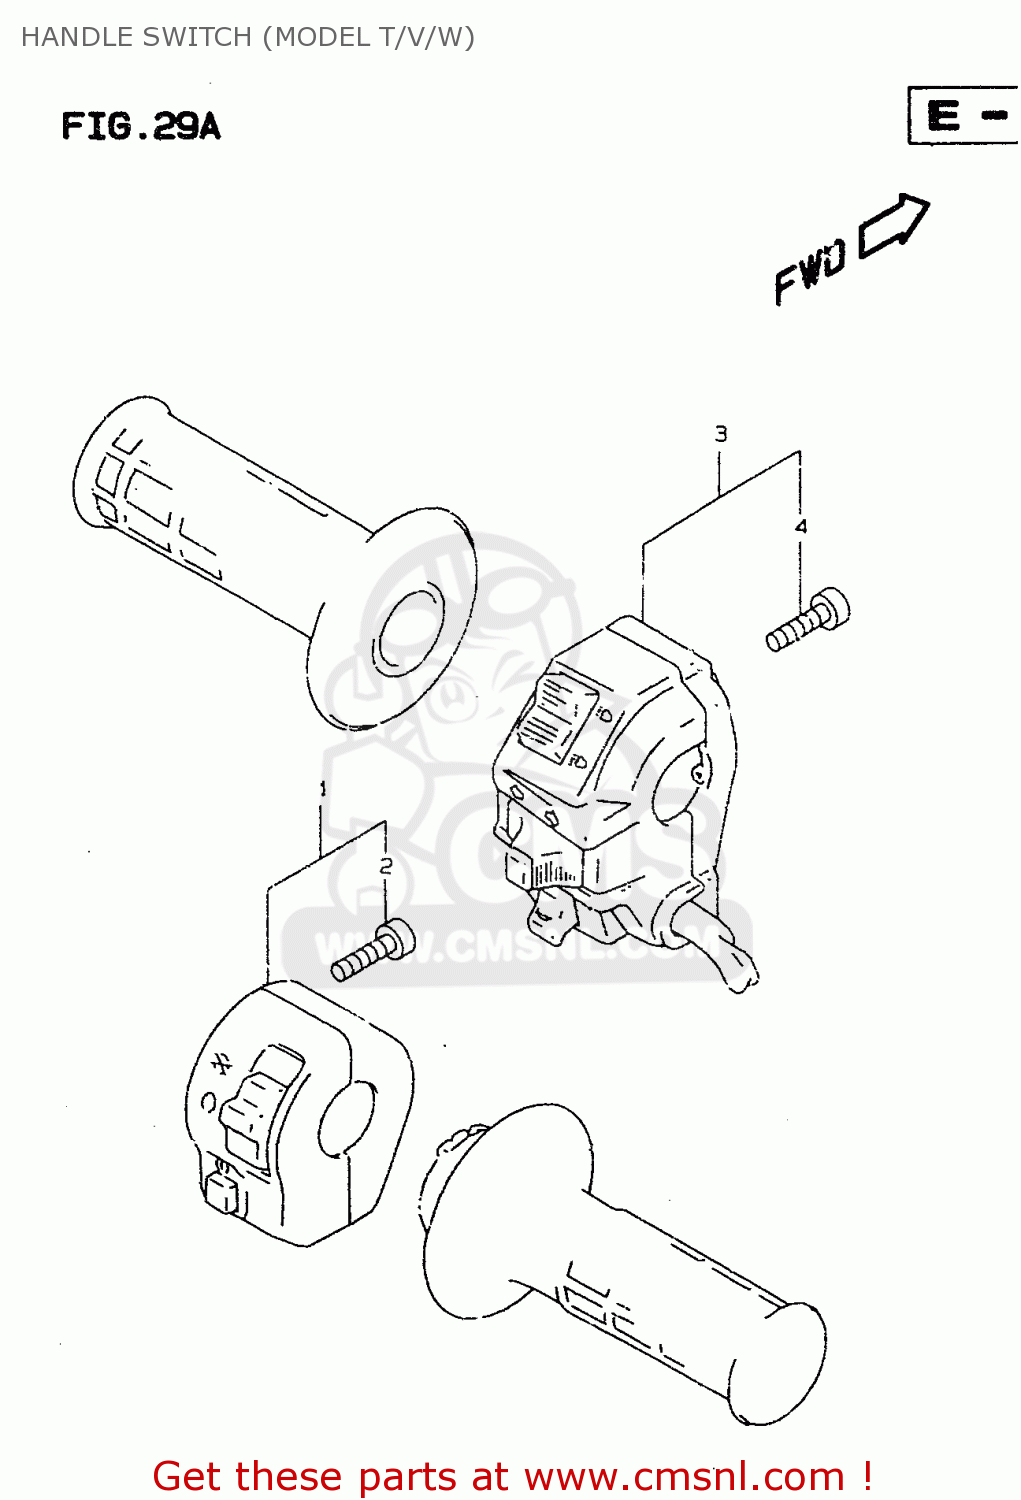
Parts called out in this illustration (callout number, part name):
1	SWITCH ASSY,HANDLE,R
2	SCREW
3	SWITCH ASSY,HANDLE,L
4	SCREW
